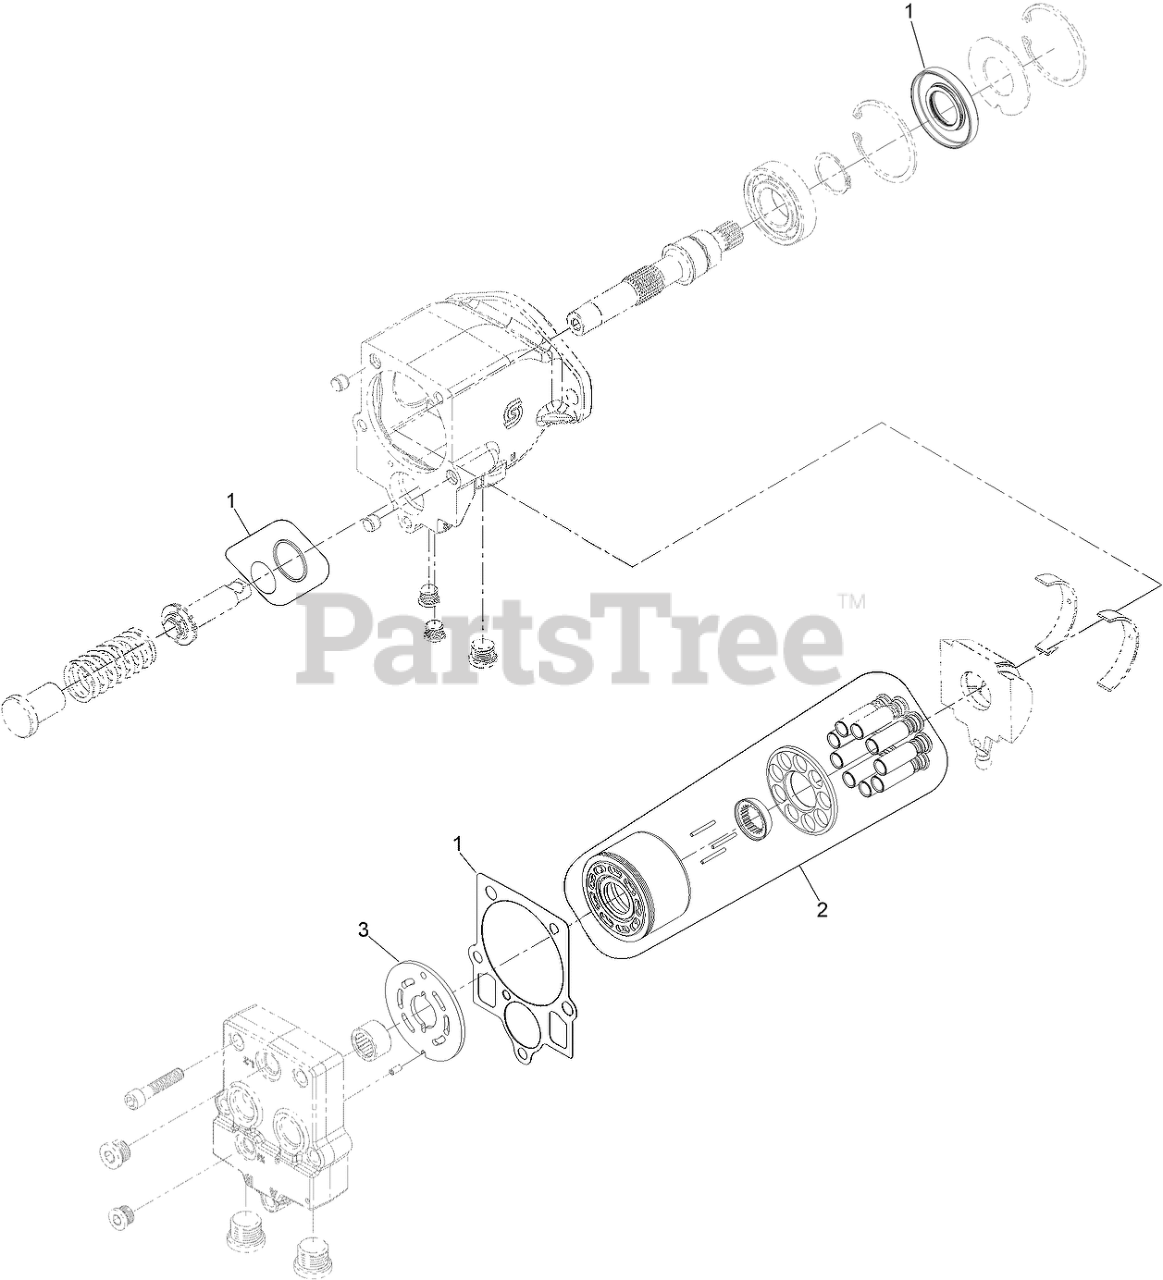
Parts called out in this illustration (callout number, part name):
1	SEAL KIT-HYD MOTOR
2	ROTATING GROUP
3	VALVE PLATE
